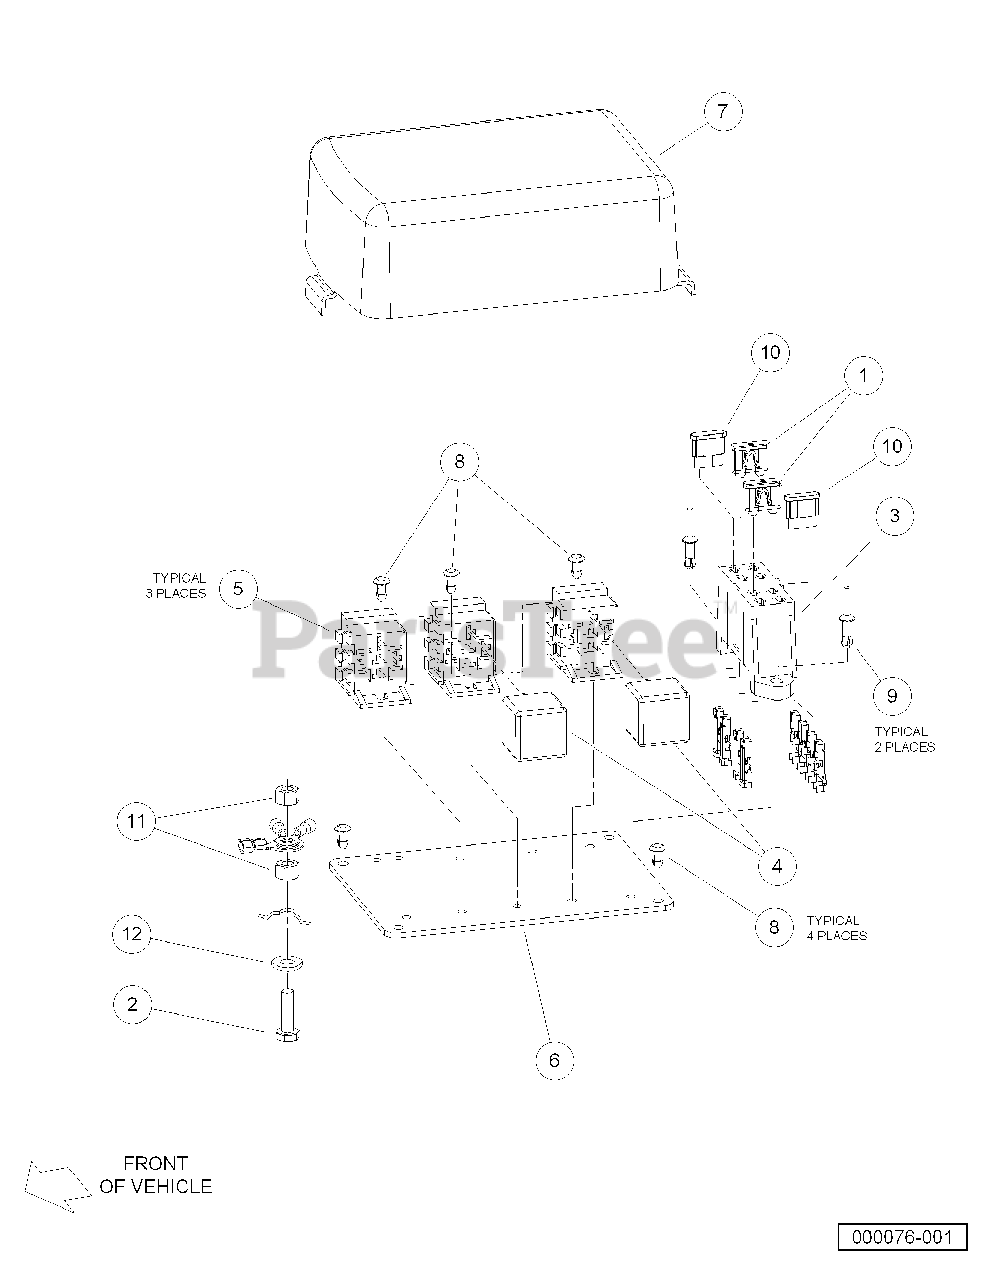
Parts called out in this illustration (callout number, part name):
1	Fuse, 10-Amp
2	Screw, 1/4-20 X .88 Hex Hd Cap
3	Fuse Block
4	Relay, Mini ISO, SPDT
5	Connector, Relay
6	Plate, Electrical
7	Cover, Electrical
8	Fastener, Push-in
9	Rivet, Drive
10	Fuse, 25-Amp
11	Locknut, 1/4-20 Dimpled
12	Washer, 1/4 Type A Narrow Flat
